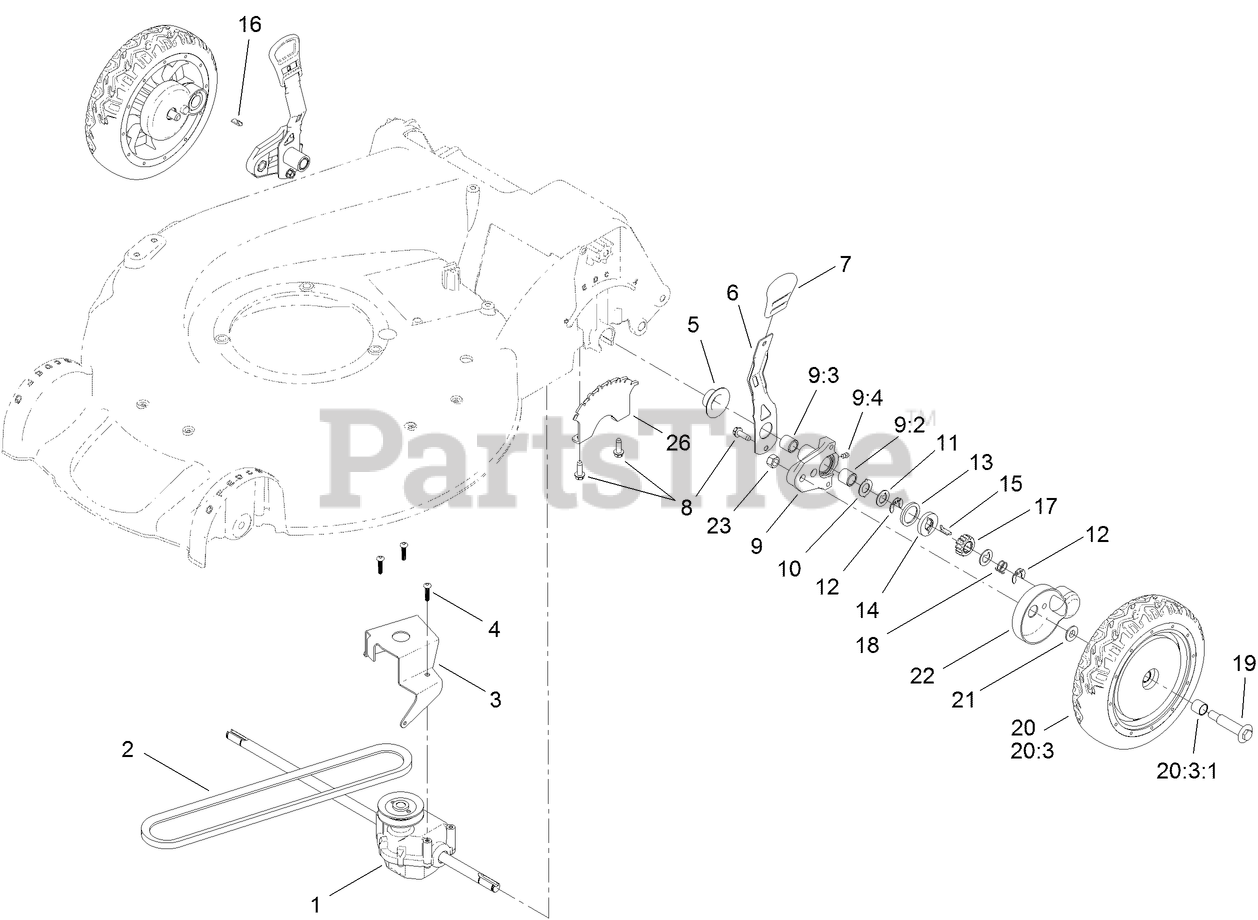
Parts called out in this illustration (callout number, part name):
1	TRANSMISSION ASM
2	V-BELT
3	BRACKET-TRANSMISSION
4	SCREW-PLASTITE
5	CAP-END
6	ARM-SPRING
7	KNOB-HOC
8	SCREW-HWHTF
9	PIVOT ARM ASM
9:2	BUSHING
9:3	BUSHING
9:4	FITTING-GREASE
10	WASHER-ARM, PIVOT
11	WASHER-THRUST, KEYED
12	RING-RETAINING,CLIP
13	RING-FRICTION
14	WASHER-CLUTCH
15	KEY-ROCKING, LH
16	KEY-ROCKING, RH
17	GEAR-PINION
18	SPRING-COMPRESSION
19	BOLT-SHOULDER
20	WHEEL GEAR ASM
20:3	Loose Parts Package
20:3:1	BUSHING
21	SPACER-COVER, WHEEL
22	COVER-WHEEL
23	LOCKNUT
26	PLATE-HOC
